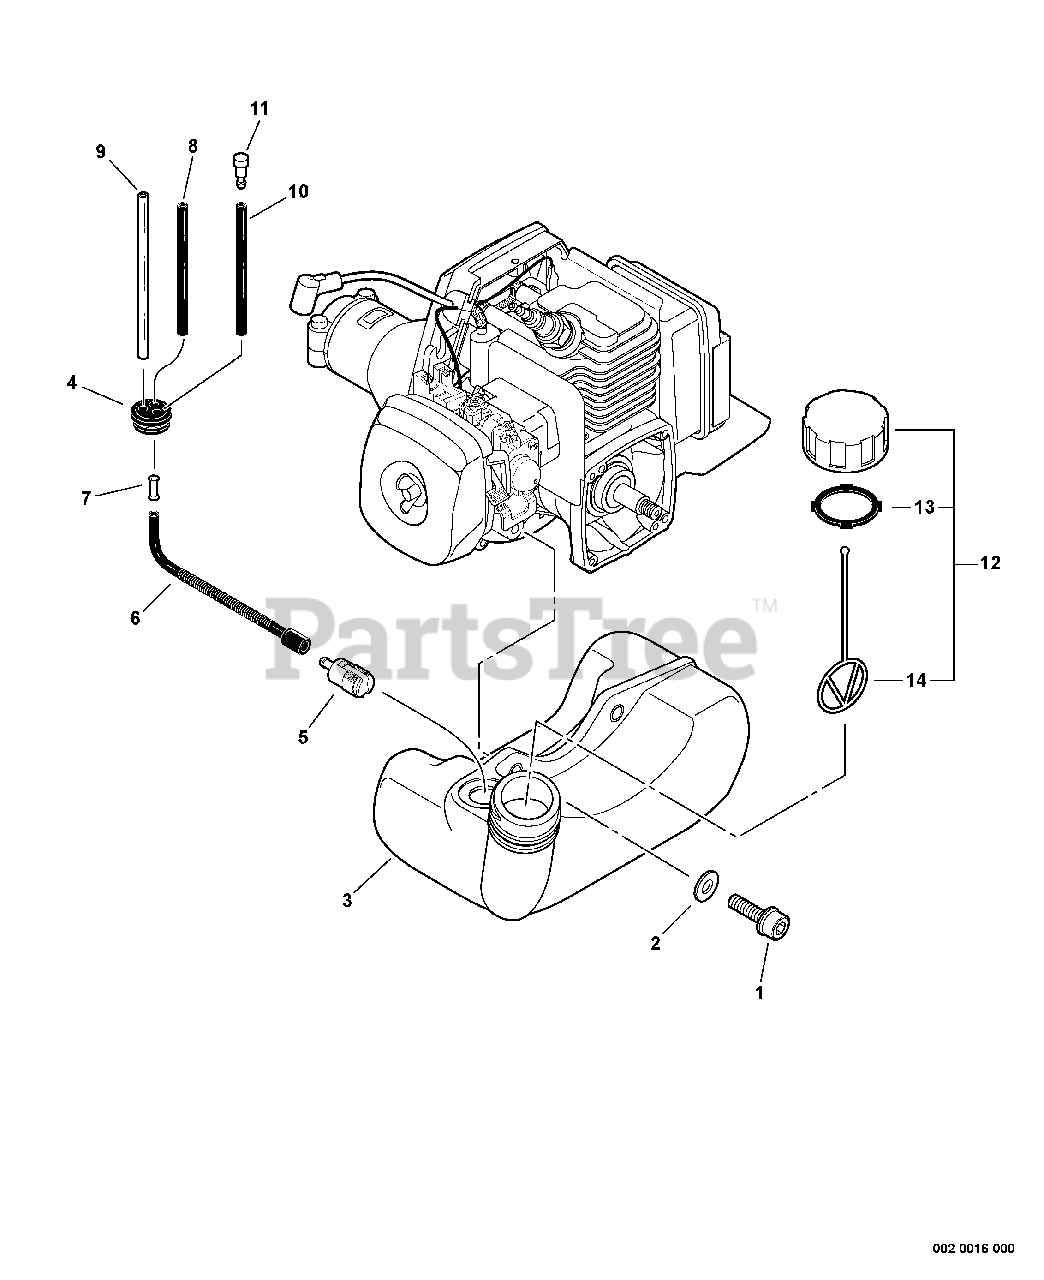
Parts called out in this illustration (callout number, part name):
1	BOLT 5×20
2	WASHER 5.5×12×0.8
3	TANK, FUEL
4	GROMMET, FUEL
5	FILTER, FUEL
6	PIPE, FUEL 3×7×100 FLEXIBLE
7	CONNECTOR, PIPE
8	PIPE, FUEL 3x-5x-70 BLACK
9	PIPE, FUEL 3×6×80 CLEAR
10	PIPE, FUEL 3x-5x-70 BLACK
11	VENT ASSY
12	CAP ASSY, FUEL
13	GASKET, FUEL CAP
14	CONNECTOR, CAP L= 100 MM
